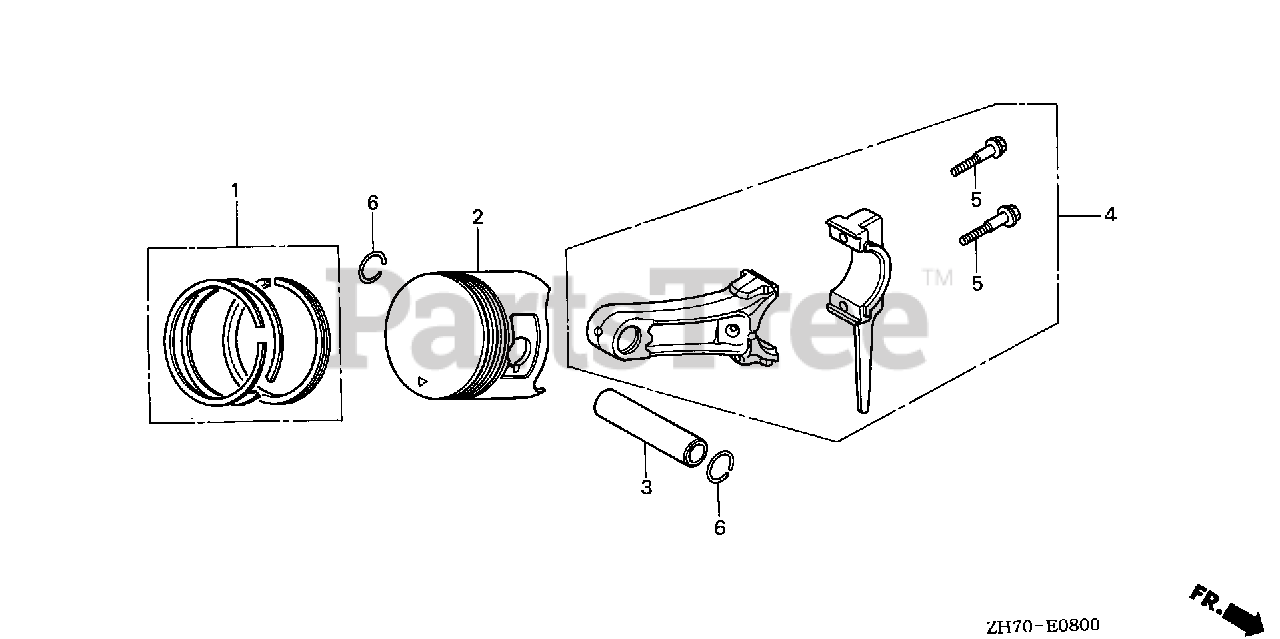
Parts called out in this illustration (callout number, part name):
1	RING SET, PISTON (STD) (NIPPON)
1	RING SET, PISTON (0.25) (NIPPON)
1	RING SET, PISTON (0.25) (TEIKOKU)
1	RING SET, PISTON (0.50) (NIPPON)
1	RING SET, PISTON (0.75) (NIPPON)
1	RING SET, PISTON (0.75) (TEIKOKU)
2	PISTON (STD)
2	PISTON (0.25)
2	PISTON (0.50)
2	PISTON (0.75)
3	PIN, PISTON
4	ROD ASSY., CONNECTING (UNDER SIZE)
4	ROD ASSY., CONNECTING
5	BOLT, CONNECTING ROD
6	CLIP, PISTON PIN (13MM)
